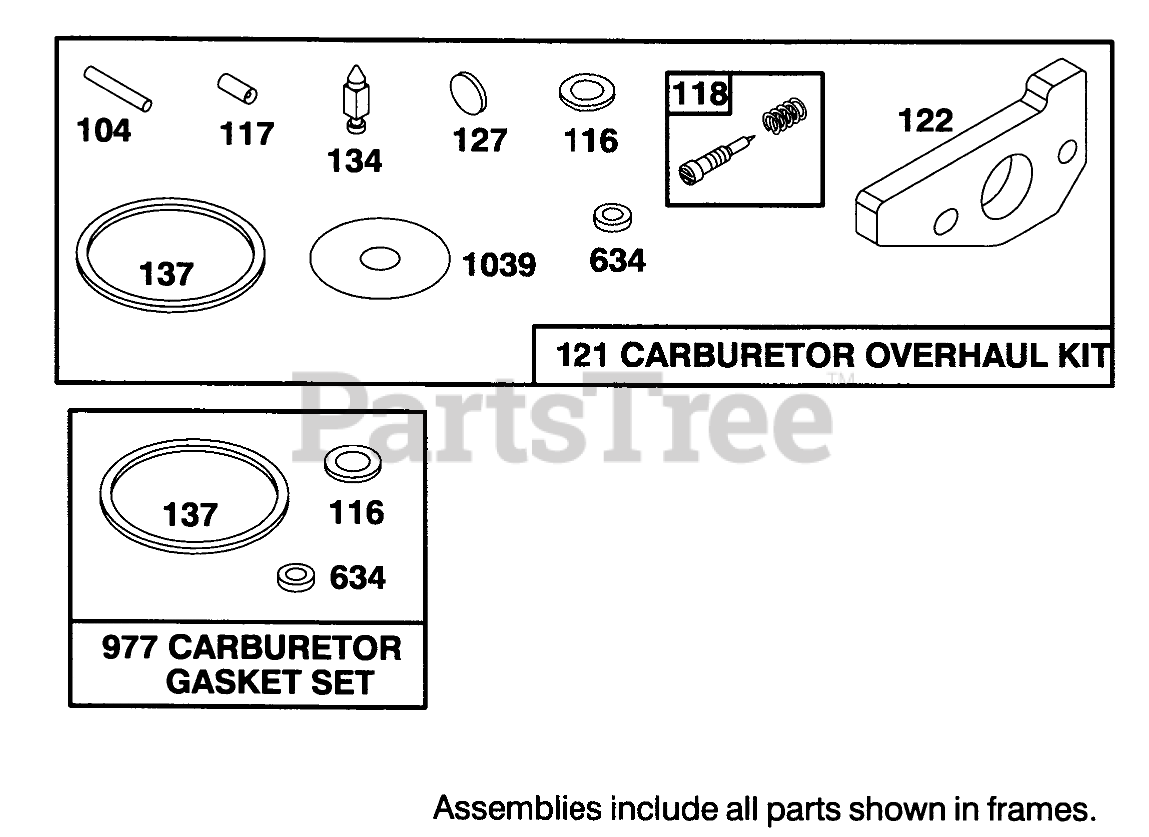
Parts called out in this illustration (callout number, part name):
104	FLOAT HINGE PIN
116	SEALING GASKET
118	VALVE KIT - NEEDLE
121	CARBURATOR OVERHAUL KIT
122	ADAPTER ASSEMBLY
134	Valve-Float (Includes Seat)
137	FLOAT BOWL GASKET
634	SEAL WASHER
977	CARBURATOR GASKET SET
1039	FLOAT LIMITER
